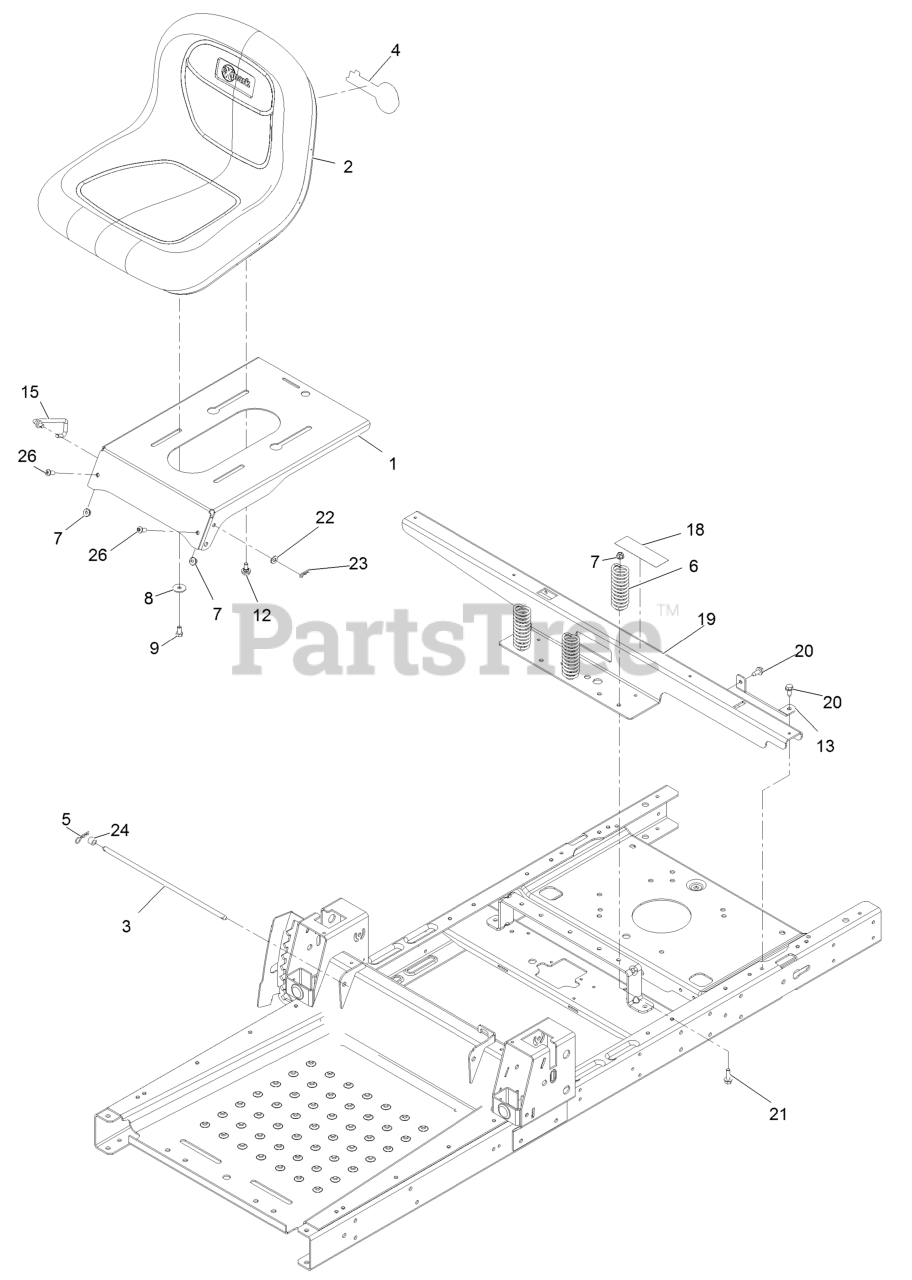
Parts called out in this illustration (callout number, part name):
2	SEAT-15 IN
3	ROD-STOP
4	DECAL-EXMARK LOGO
5	PIN-COTTER
6	SPRING-COMPRESSION
7	NUT-HF, NI
8	WASHER-PIVOT
9	SCREW-HH
12	BOLT-SHOULDER,HFH
13	SUPPORT-TANK, REAR
15	STOP-SEAT
18	DECAL-SERVICE, CE
19	SUPPORT-POD, WIDE
20	Screw-HWH 5/16-18 X 3/4 Tf
21	SCREW-HHF
22	WASHER-PLAIN
24	BUSHING-LEVER, LIFT
26	SCREW-HSBH
